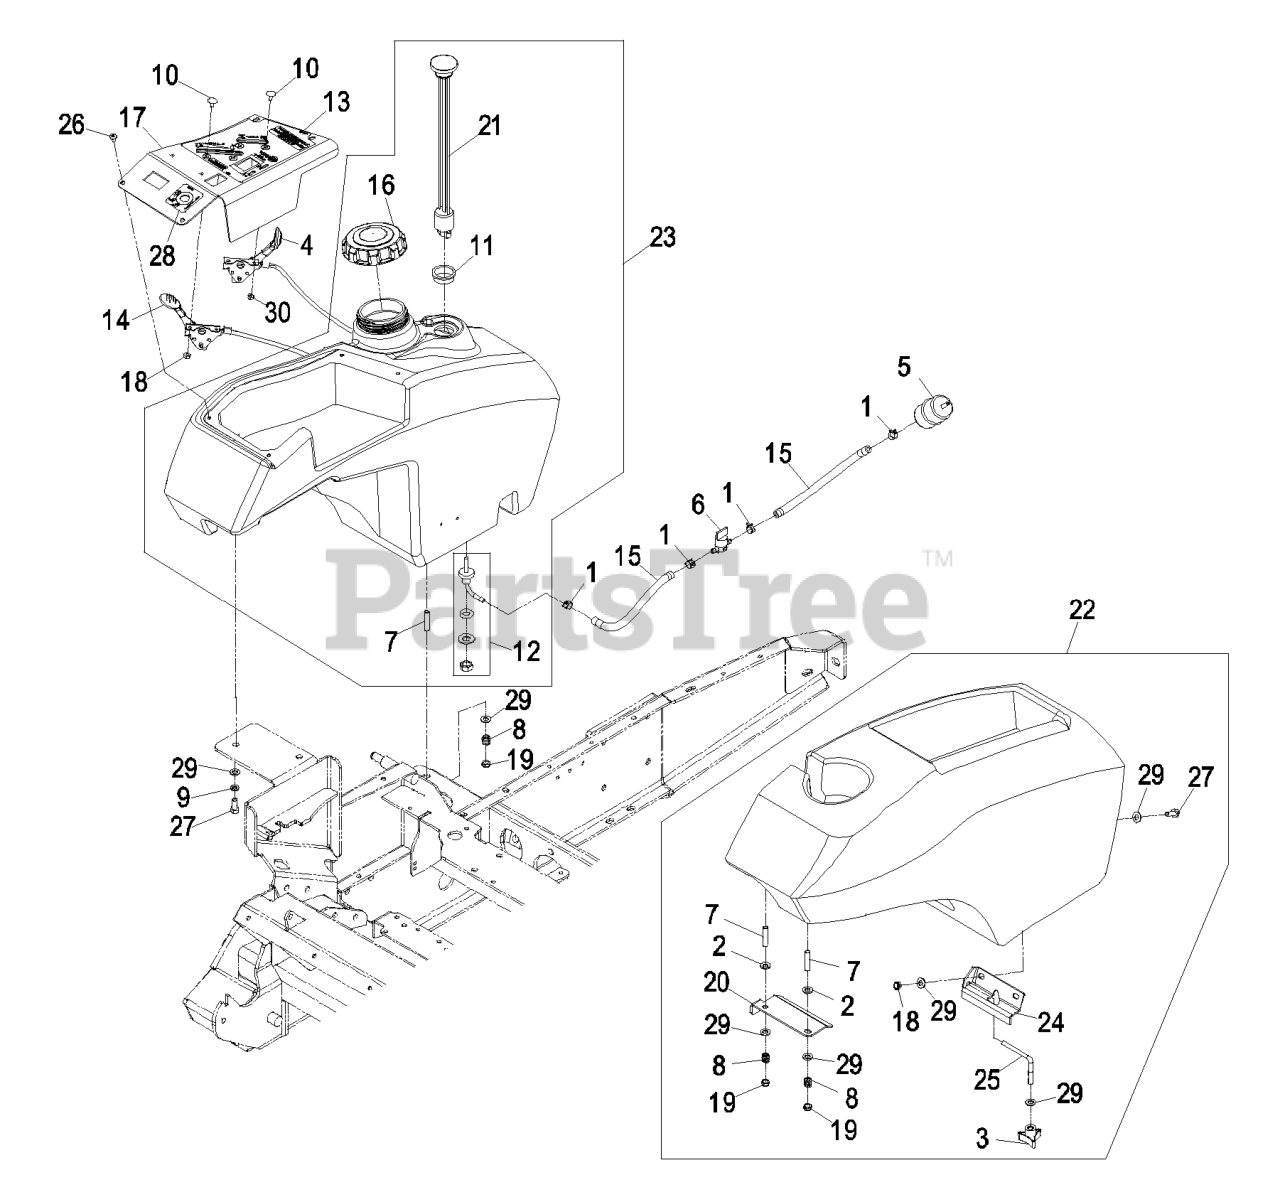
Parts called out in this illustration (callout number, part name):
2	WASHER-SPRING
3	KNOB-3 PRONG
4	CONTROL,CHOKE
5	Kohler Part No. 2405010 Fuel Filter
6	VALVE-FUEL
7	STUD
8	SPRING-TANK, FUEL
9	WASHER-LOCK
10	BOLT-CARR
11	CONTACT ORDER SERVICES
12	FITTING-FUEL, BULKHEAD
13	DECAL,CONTROL FMZ A/C
14	CONTROL,THROTTLE
15	HOSE-FUEL
16	CAP-FUEL, GAS
17	ASM,CONTROL PANEL FMZ A/C
18	NUT-LOCK, NI
19	NUT-LOCK, NI
20	HOOK,FENDER (PLATED)
21	Gauge, Fuel
22	ASM,FENDER FMZ
24	BRACKET,FENDER
25	BOLT,FENDER
26	SCREW-PPH
27	SCREW-HH
28	DECAL,IGNITION
29	WASHER-PLAIN
